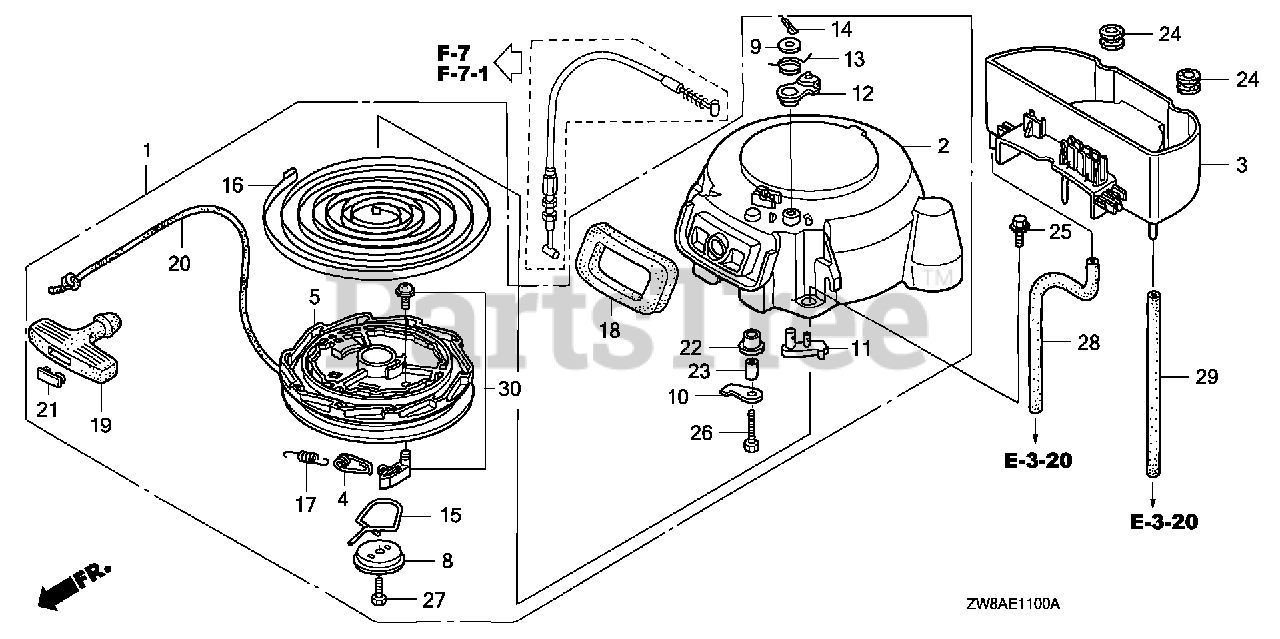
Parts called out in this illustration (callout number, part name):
1	STARTER ASSY., RECOIL
2	CASE, RECOIL STARTER
3	CASE B, STARTER
4	GUIDE, RECOIL STARTER
5	REEL, RECOIL STARTER
6	RATCHET SET, STARTER
6	RATCHET, STARTER
7	RATCHET SET, STARTER
7	E-RING
8	PLATE, FRICTION
10	WASHER, THRUST
11	STOPPER, REEL
12	ARM, STOPPER
13	SPRING, STOPPER
14	PIN, SPLIT
15	SPRING, FRICTION
16	SPRING, RECOIL STARTER
17	SPRING, RETURN
18	SEAL, RECOIL
19	GRIP, STARTER
20	ROPE, RECOIL STARTER (N/A: USE P/N 08550-ZG921-11)
21	CAP, STARTER KNOB
22	ROLLER, STARTER
23	GUIDE, ROLLER
24	GROMMET, ENGINE COVER
25	BOLT, FLANGE (6X22)
26	BOLT, HEX. (6X25)
27	BOLT, HEX. (6X14)
28	TUBE, WATER DRAIN
29	BULK HOSE, VACUUM (8X1000) (8X240)
30	RATCHET SET, STARTER
